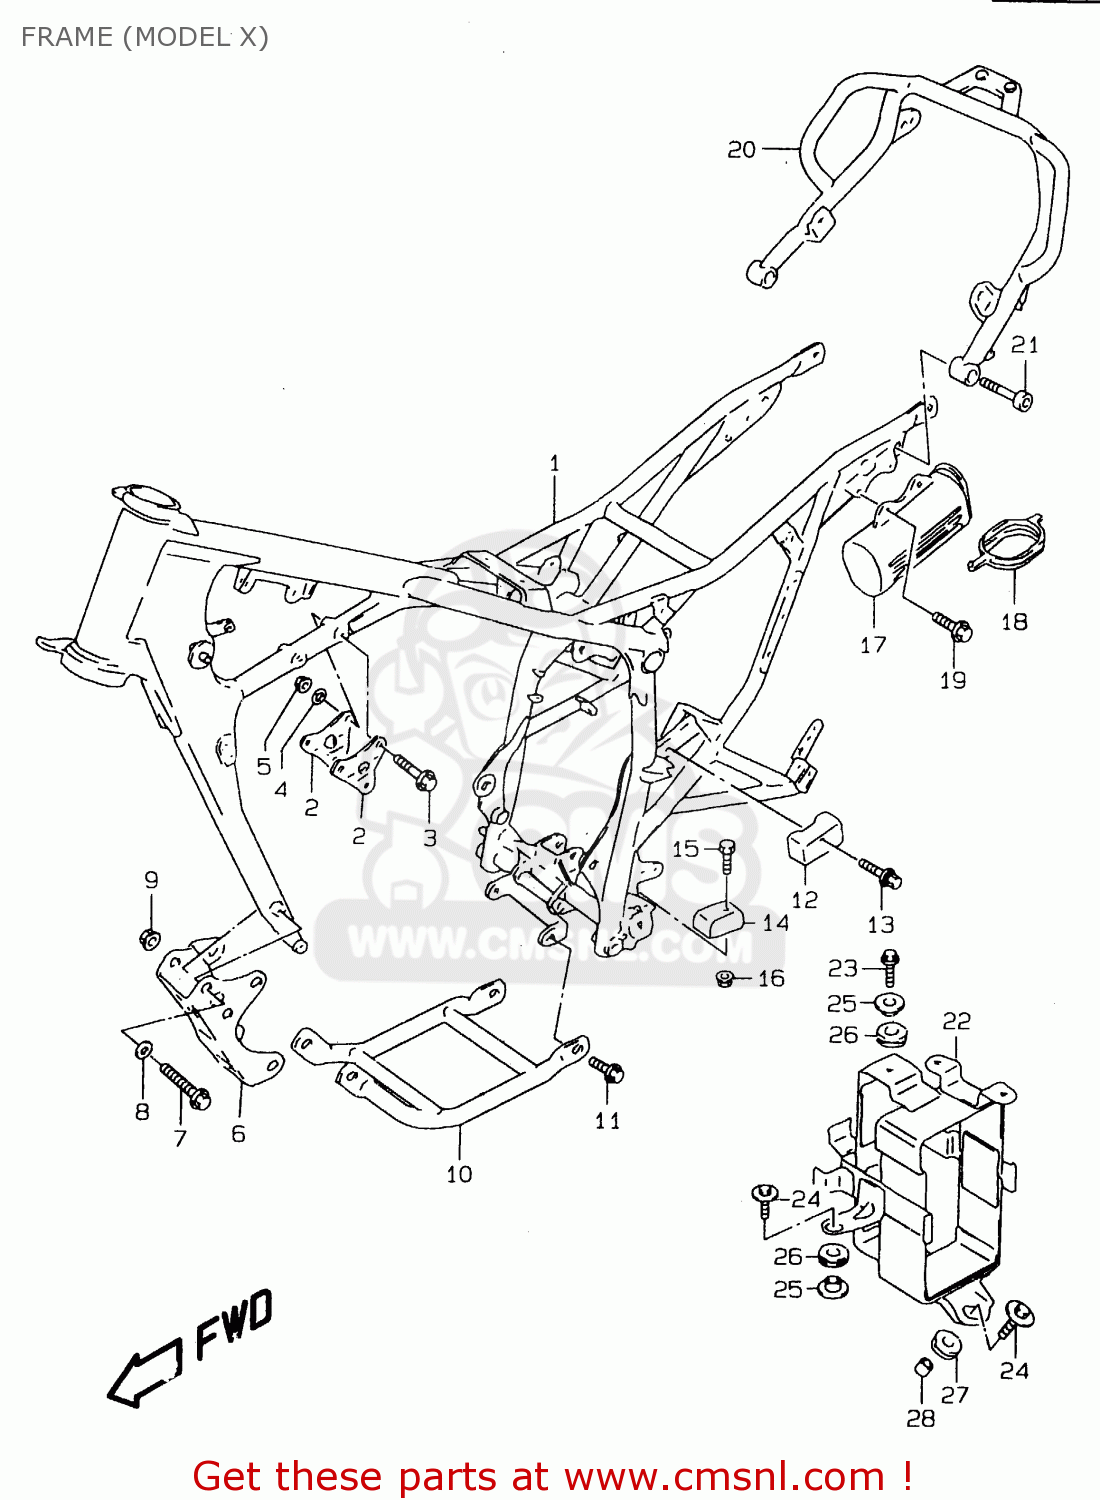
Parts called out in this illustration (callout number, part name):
1	FRAME(CHARCOAL)
2	PLATE,ENGINE MOUNT UPR
3	BOLT(8X53)
4	LOCK WASHER
5	NUT
6	PLATE,ENGINE MOUNT LWR
7	BOLT(8X65)
8	LOCK WASHER
9	NUT
10	PROTECTOR ENGINE(CHARCOAL)
11	BOLT
12	GUIDE,CH CONTROL UPR
13	BOLT
14	GUIDE,CH LENGTH CONTROL LWR
15	BOLT
16	NUT
17	HOLDER,TOOL
18	CAP,HOLDER
19	BOLT 6X16
20	GRIP,RR
21	BOLT(8X30)
22	HOLDER,BATTERY
23	BOLT
24	BOLT(6X25)
25	WASHER
26	CUSHION
27	CUSHION
28	SPACER(6.5X10X9)
